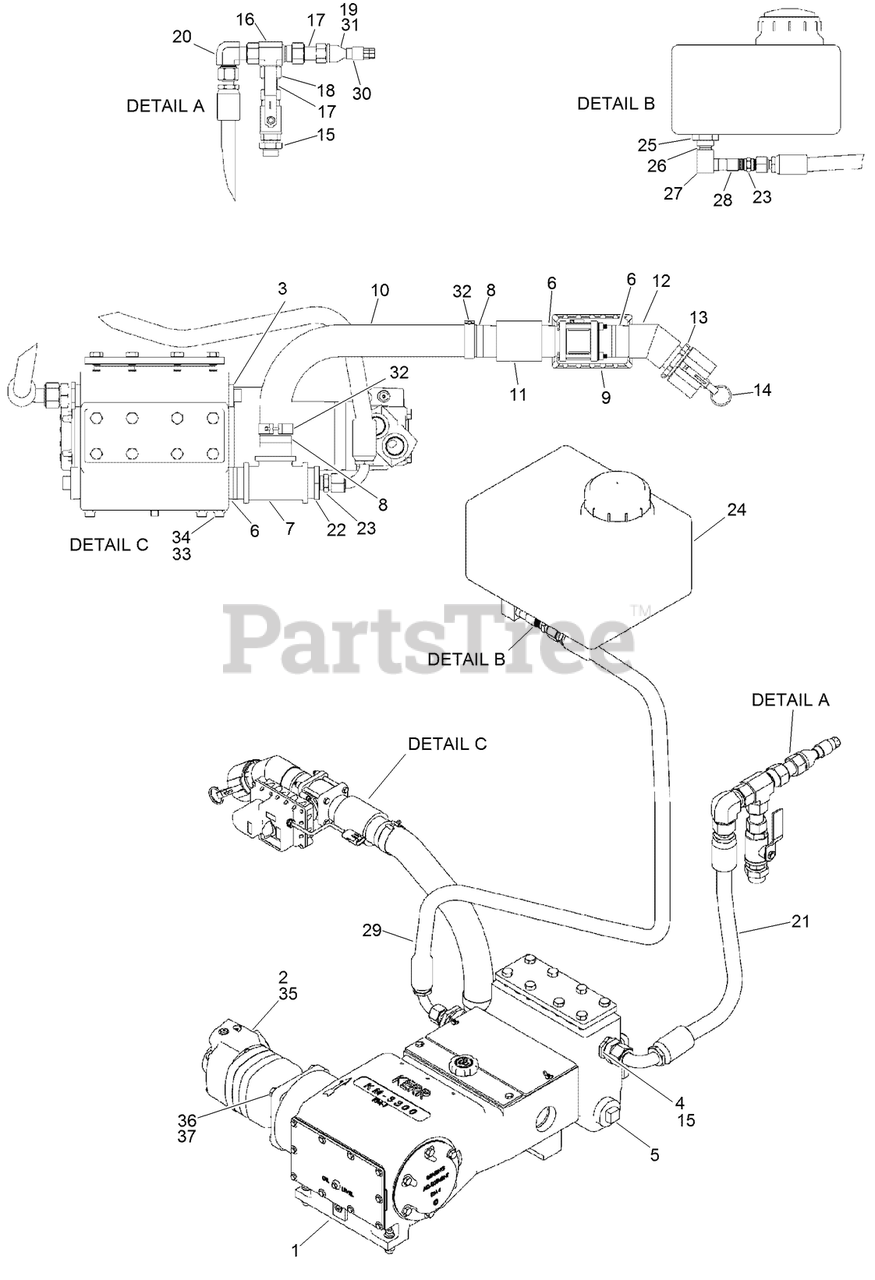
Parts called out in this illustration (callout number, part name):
1	PUMP - Mud (Kerr KM3300)
2	HYD MOTOR ASM
3	PLUG - Sq Hd Pipe 1-1/4 - 11.5 NPTF STL PLN
4	FITTING-REDUCER
5	PLUG-PIPE, SQUARE HEAD
6	NIPPLE-PIPE
7	TEE-PIPE
8	NIPPLE-COMBINATION
9	2 INCH BALL VALVE ASM (ELECTRIC)
10	HOSE - Tank to Pump
11	COUPLING - Pipe, Hi Pressure, NPT
12	ELBOW-PIPE-45
13	ADAPTER-MALE
14	CAP-CONNECT, QUICK
15	FITTING-STRAIGHT
16	FITTING-TEE, BULKHEAD
17	FITTING-STRAIGHT
18	VALVE-BALL
19	FITTING-REDUCER
20	CONNECTION - 90 Degree, -16 ORFS / -16 ORFS
21	HOSE ASM-HYD
22	FITTING-REDUCER
23	FITTING-STRAIGHT
24	TANK - 6G, No Fitting - Poly
25	FITTING-TANK, BULKHEAD (PLASTIC)
26	NIPPLE-STRAIGHT
27	ELBOW-STREET, 90 DEG
28	VALVE-BALL
29	HOSE - Tank to Pump
30	NIPPLE-CONNECT, QUICK
31	CAP-DUST, PLASTIC
32	CLAMP-HOSE, T-BOLT
33	SCREW-FLANGE
34	NUT-FLANGE, NYLOCK
36	WASHER-Spring Lock Reg 1/2 ZND
